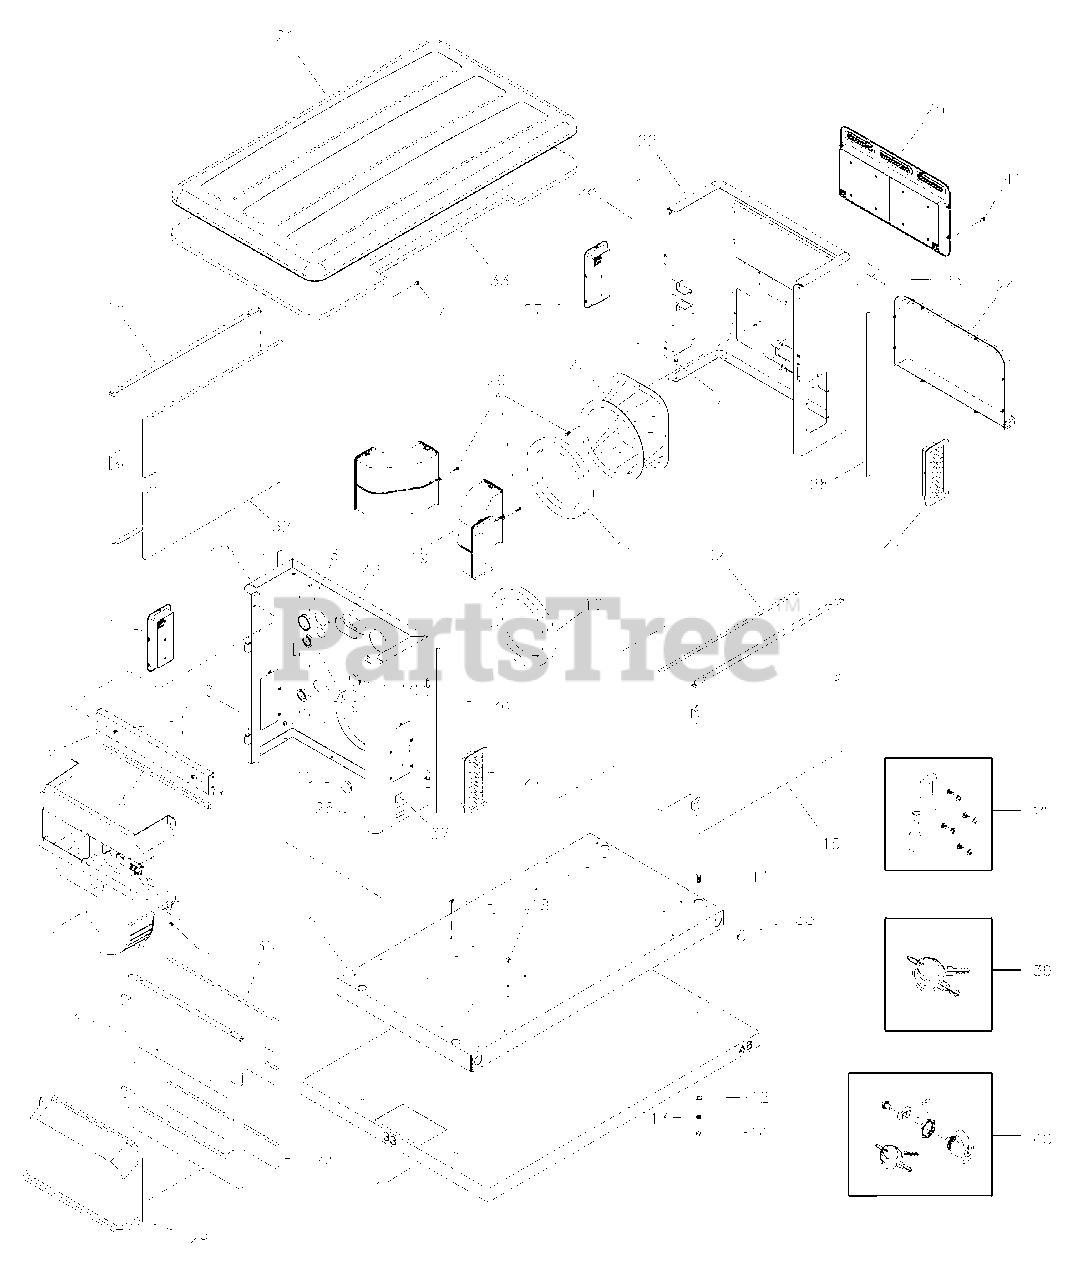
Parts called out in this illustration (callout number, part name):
2	BASE
3	BULKHEAD, Engine
4	DOOR
5	DUCT
6	SUPPORT, Rail
7	BOLT
11	* CAPSCREW, Hex Head, 3/8-16 x 1
12	* WASHER, Flat, 3/8-M10
13	* WASHER, Lock, 3/8
14	* NUT, 3/8-16
15	DOOR
18	MOUNT, Tie Wrap
20	ADAPTER, Engine
21	ROOF
22	BULKHEAD, Alternator
24	COVER, Air Intake
29	COVER, Air Intake
37	DECAL
41	SCREW
